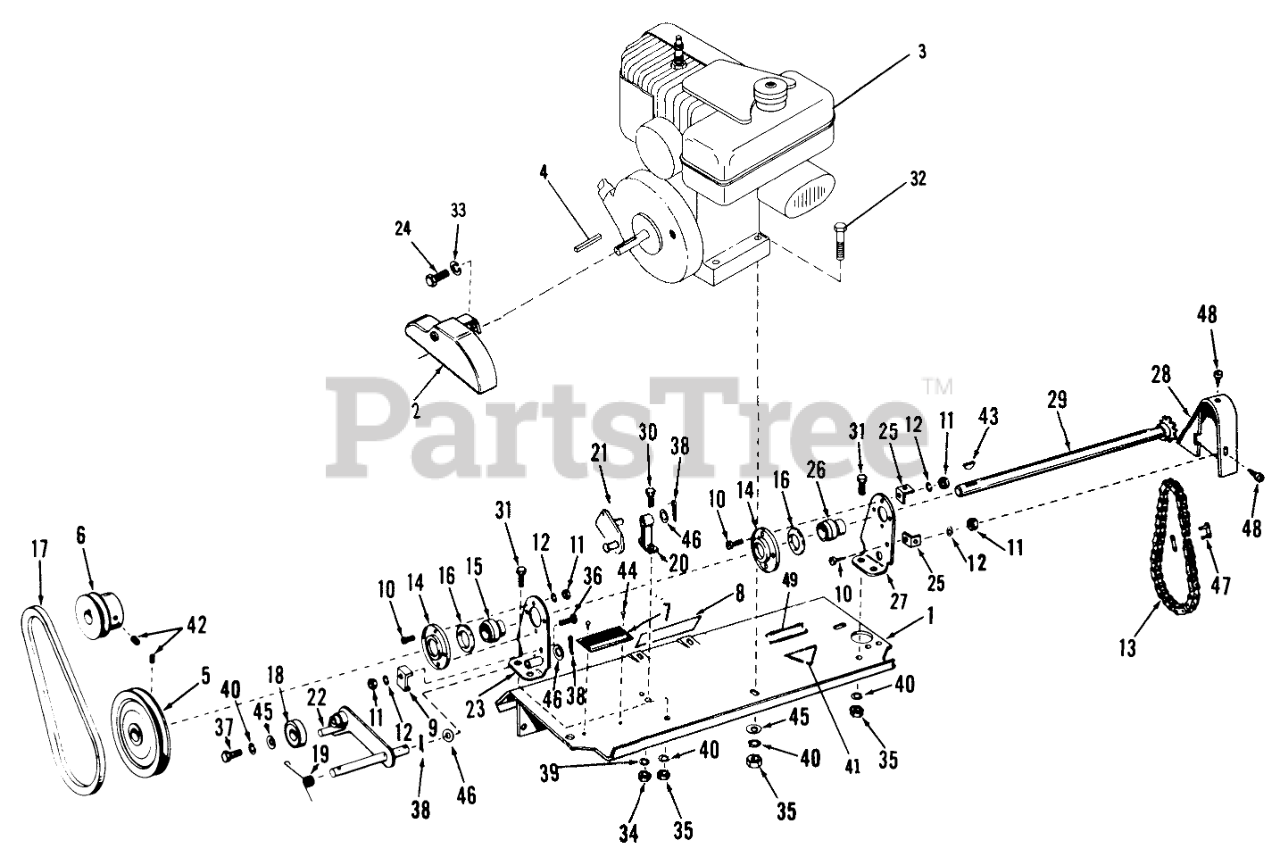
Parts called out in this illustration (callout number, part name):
1	Deck Assembly
2	RUBBER BOOT
3	Engine Assembly
4	Key, Crankshaft Pulley
5	Pulley, Cross Shaft
6	Pulley, Crankshaft
7	Plate, Serial Number
8	MANUAL
9	Clamp, Clutch Cable
10	Screw-Rd. Hd. #10-24 x 3/8
11	Nut #10-24
12	Lockwasher, #10 Type 12
13	T96-16G MAIN DRIVE GEAR
14	Cover, Cross Shaft Bearing
15	Bearing Cross Shaft, L.H.
16	Felt, Oil Retaining
17	Belt, Drive
18	Bearing, Idler
19	Spring, Belt Tightener
20	Bracket, Bell Crank
21	Crank, Bell
22	Shaft & Arm, Clutch
23	Cross Shaft Brkt. Assembly
24	Screw 1/2 20 x 5/8
25	Clip, Upper Chain Guard
26	PILOT BRG ROLLER
27	Bracket, Bearing, Cross Shaft
28	Guard, Chain, Upper
29	Shaft, Cross w/Sprocket
30	Bolt-1/4-20 x 5/8
31	Bolt Hex 5/16-18
32	Bolt 5/16-18 x 1/2
33	Lockwasher
34	Nut 1/4-20
35	Nut, 5/16-18
36	Screw, #10-24 x 3/4 Rd. Hd. Machine
37	Bolt-Round Head 5/16-18 x 1/2
38	Cotter Pin
39	Lockwasher
40	Lockwasher
41	Decal, Safety, ASA
42	Set Screw
43	Key, #6 Woodruff
44	Screw, #2 x 1/4, Type U-Drive
45	Washer, 5/16 Burr
46	Washer
47	Link, Master-Drive Chain
48	Screw, #10 x 1/2 Truss Hd.
49	Decal Caution
